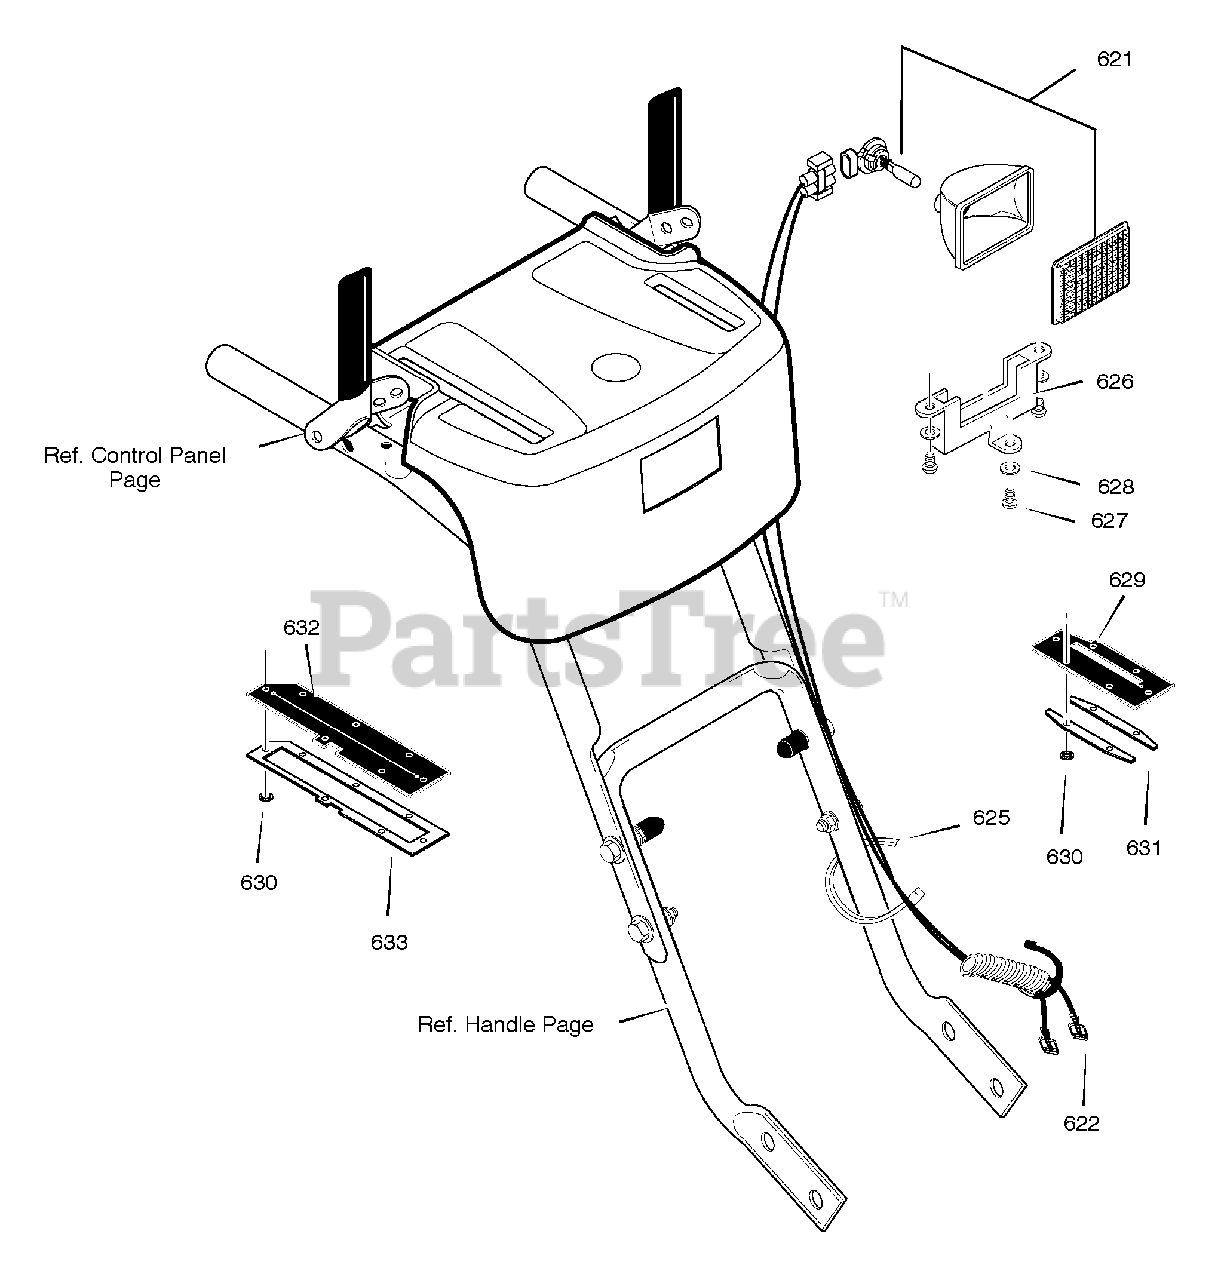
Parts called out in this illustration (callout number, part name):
621	LIGHT, HALOGEN
622	HARNESS, WIRE
625	TIE, CABLE
626	BRACKET, LIGHT
627	SCREW #8 X .50
628	WASHER, FLAT
629	COVER, CHUTE LEVER
630	NUT, PUSH
631	FRAME, COVER
632	COVER, SPEED LEVER
633	FRAME, SPEED COVER
